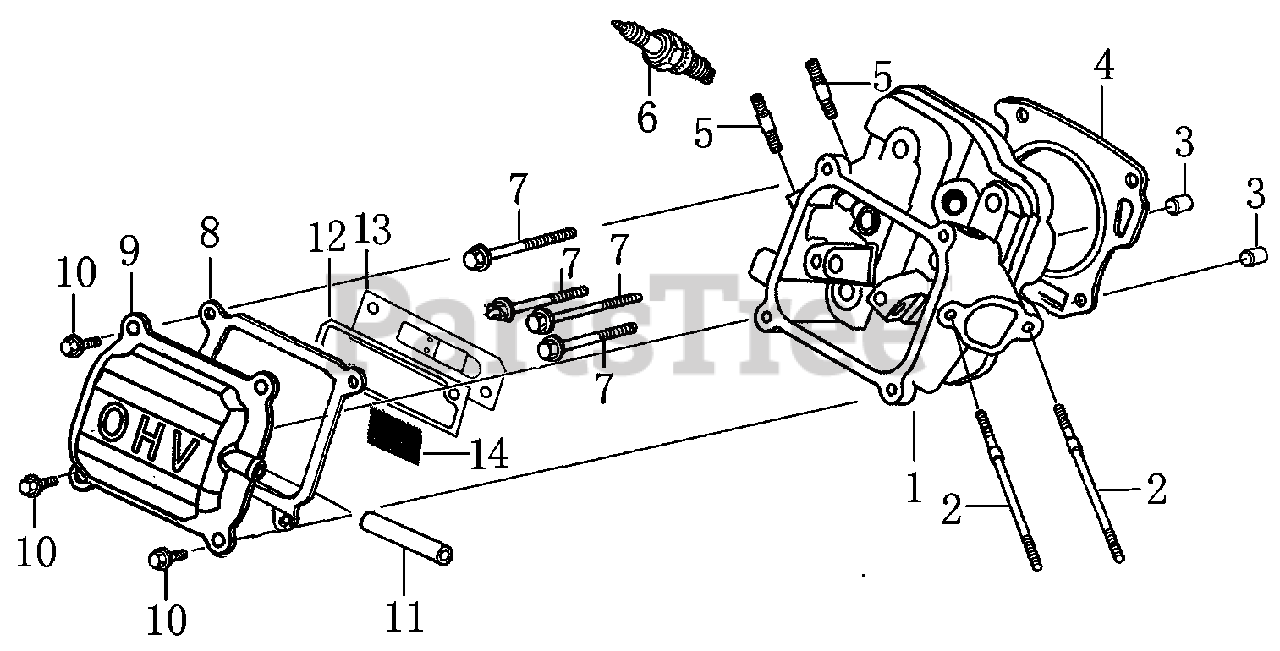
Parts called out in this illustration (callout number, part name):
1	HEAD, CYLINDER
2	BOLT, STUD, INTAKE
3	PIN, DOWEL
4	GASKET, CYLINDER HEAD
5	BOLT, STUD, EXHAUST
6	PLUG, SPARK
7	BOLT, FLANGE HEAD, 8*60
8	GASKET, HEAD COVER
9	COVER, HEAD
10	BOLT, FLANGE, 6*14
11	TUBE, BREATHER
12	GASKET, BREATHER CHAMBER
13	CAP, BREATHER CHAMBER
14	OIL STRAINER
